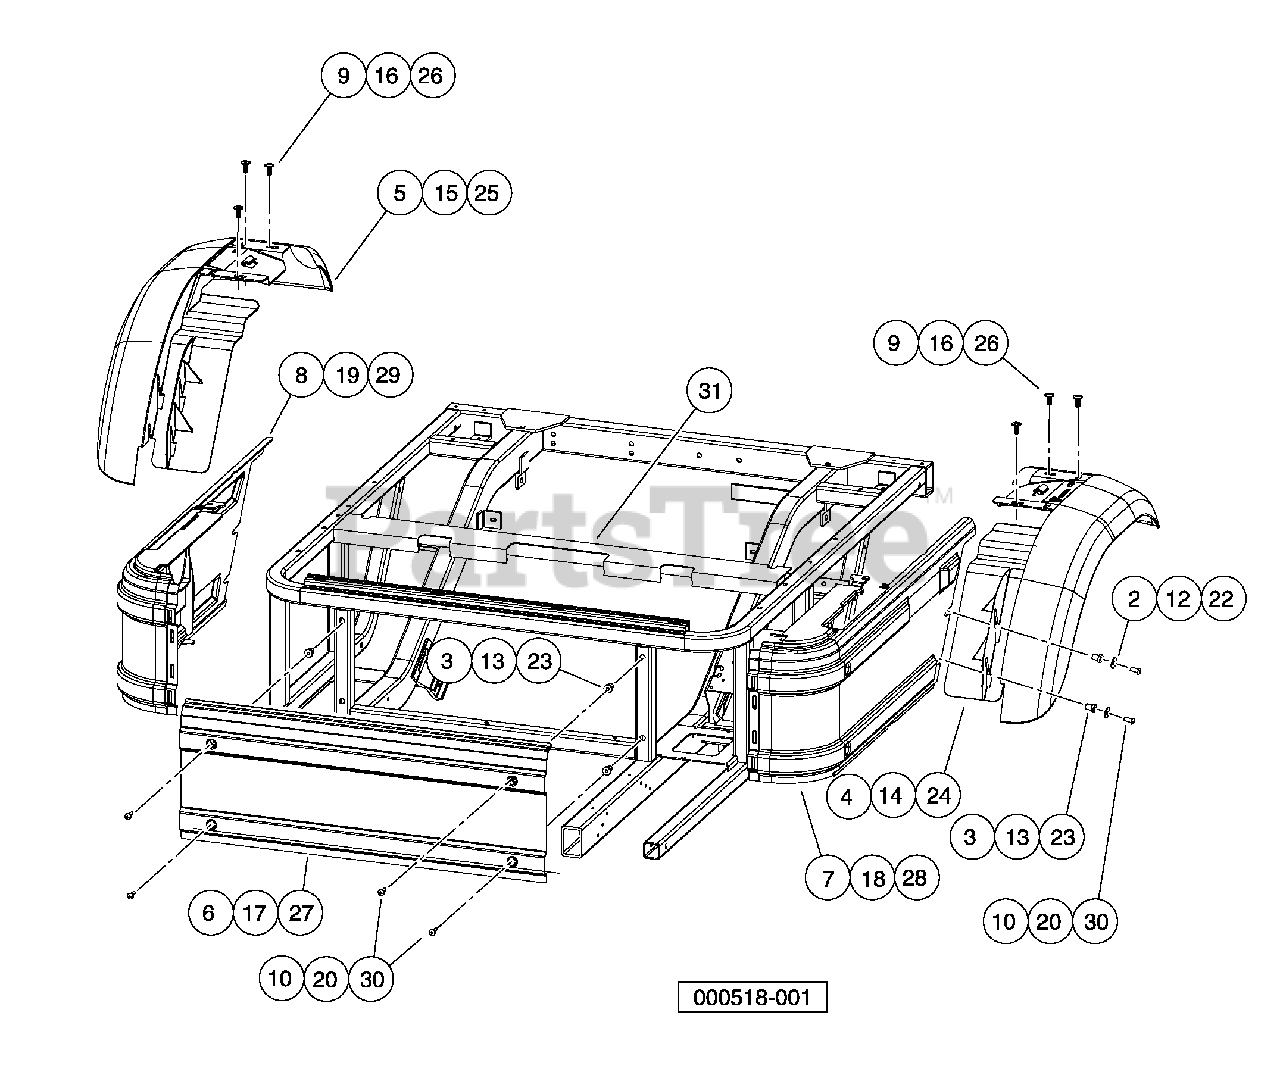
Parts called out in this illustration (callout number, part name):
1	Instl, Panels, Fenders, Blk
2	Washer, 1/4" Type B Flat
3	Well Nut 1/4-20
4	Left Rear Fender
5	Right Rear Fender
6	Panel, Front, Kick
7	Panel, Side, Molded, Driver
8	Panel, Side, Molded, Passenger
9	Screw, Tuflok, 10mm
10	Screw, 1/4-20 X 1.0 Truss-Head Machine
11	Instl, Panels, Fenders, Rthwd
12	Washer, 1/4" Type B Flat
13	Well Nut 1/4-20
14	Left Rear Fender
15	Right Rear Fender
16	Screw, Tuflok, 10mm
17	Panel, Front, Kick, Rthwhd
18	Pnl, Side, Mld, Drv, Rthwhd
19	Pnl, Side, Mld, Pass, Rthwhd
20	Screw, 1/4-20 X 1.0 Truss-Head Machine
21	Instl, Panels, Fenders, Moff
22	Washer, 1/4" Type B Flat
23	Well Nut 1/4-20
24	Left Rear Fender
25	Right Rear Fender
26	Screw, Tuflok, 10mm
27	Panel, Front, Kick, Moff
28	Pnl, Side, Mld, Drv, Moff
29	Pnl, Side, Mld, Pass, Moff
30	Screw, 1/4-20 X 1.0 Truss-Head Machine
31	Closeout, Extrusion
